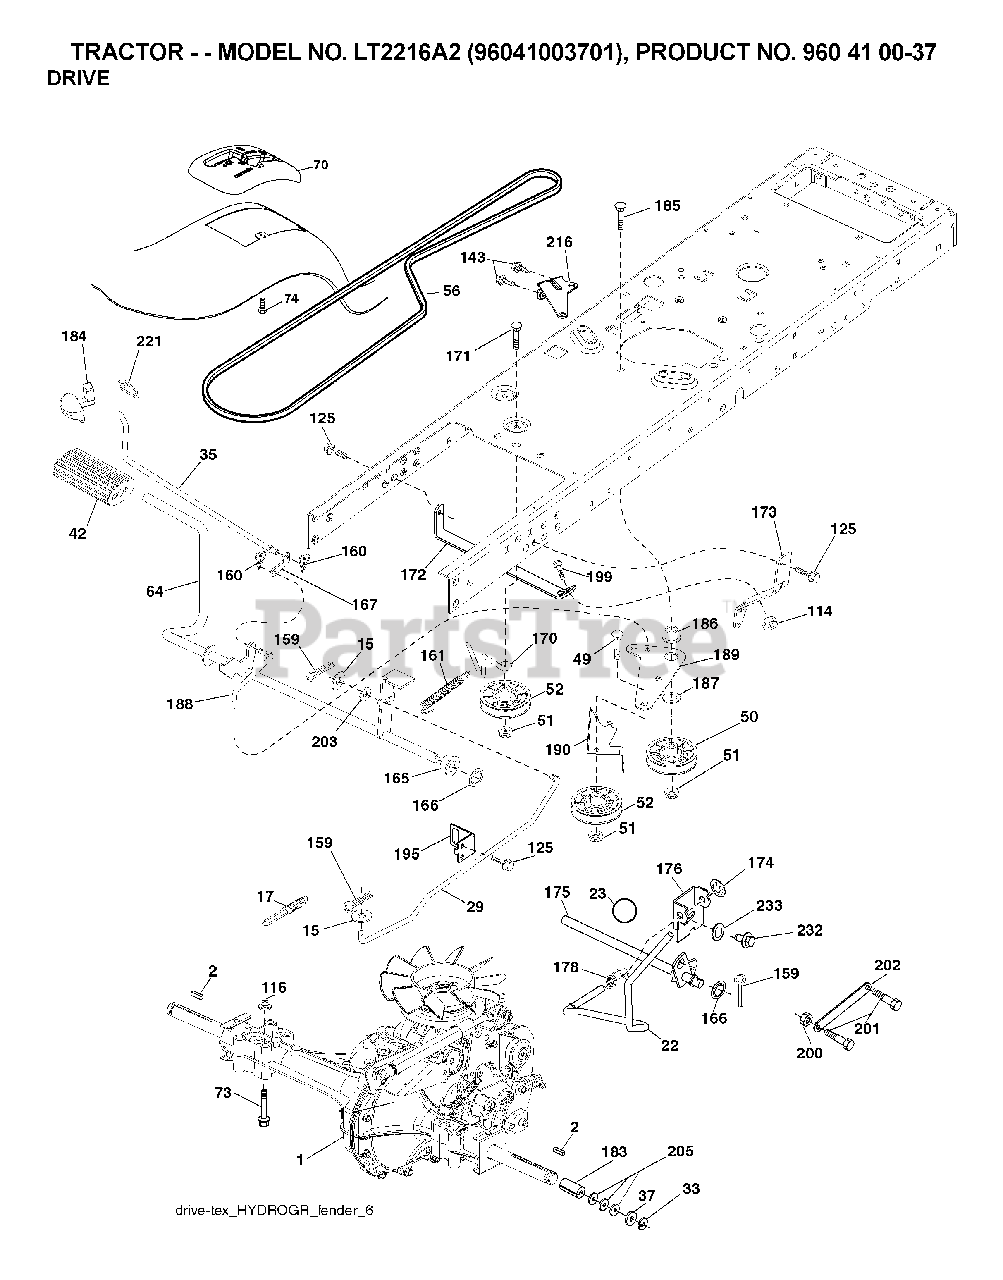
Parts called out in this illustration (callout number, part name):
2	SQUARE KEY
17	SPRING.BRAKE.HG3000/3500
22	ROD.SHIFT.FENDER.TLT.2006
23	PISTOL KNOB
29	ROD.BRAKE.HG-0510
33	E-RING LT
35	ROD.BRAKE.PARKING.LT.T
42	PEDAL COVER T
49	BOLT
50	IDLER.FLAT.910.OFFSET
51	NUT LOCK FLG 3/8-16 UNC
52	IDLER.V-GROOVE.910.OFFSET
64	SHAFT.ASM.PEDAL.BRAKE.
70	CONSOLE.SHIFT.STL.HYD.BLACK
73	BOLT HEX 5/16-18 GR 5
74	SCREW.HI-LO.CONSOLE
114	NUT.71038.31-18.HEX.NYLOCK
116	NUT LOCK HEX FLANGE 5/16-18
125	SCREW
159	COTTER PIN
160	RETAINER CLIP
161	SPRING.RETURN.CLUTCH.2006
165	BUSHING.SHAFT.BRAKE.HAND
166	NUT.PUSH.625.2006
167	LATCH.BRAKE.SPRING
170	KEEPER.V-IDLER.CENTER.
171	BOLT
172	STRAP.TRQ.LH.FS.HG0510
173	STRAP TORQUE RH
174	NUT.PUSH.500.2006
175	SHAFT.ASM.SHFT.HG0510/
176	ARM.CLEVIS.ROD.SHIFT
178	SPRING.SHIFT.GT2006
183	SPACER AXLE
184	HANDLE.PAKRING.BRAKE.
186	SPACER.RETAINER
187	WASHER 12/32X2X10GA
188	LINK.CLUTCH.GROUND.DRIVE
189	BELLCRANK.GROUND.DRIVE.TEX.
190	KEEPER.BELLCRANK.DRIVE
195	BRKT.ROD.BRAKE.18/20/2
199	BOLT
200	NUT.CENTERLOCK.5/16-
201	BOLT SHOULDER 5/16-18 UNC
203	WASHER
216	BRACKET.PULLEY.IDLER.W/TEX
221	RETAINER.SPRING.CLIP.H
232	BOLT FIN HEX 7/16-14 X 1
233	WASHER SERRATED
